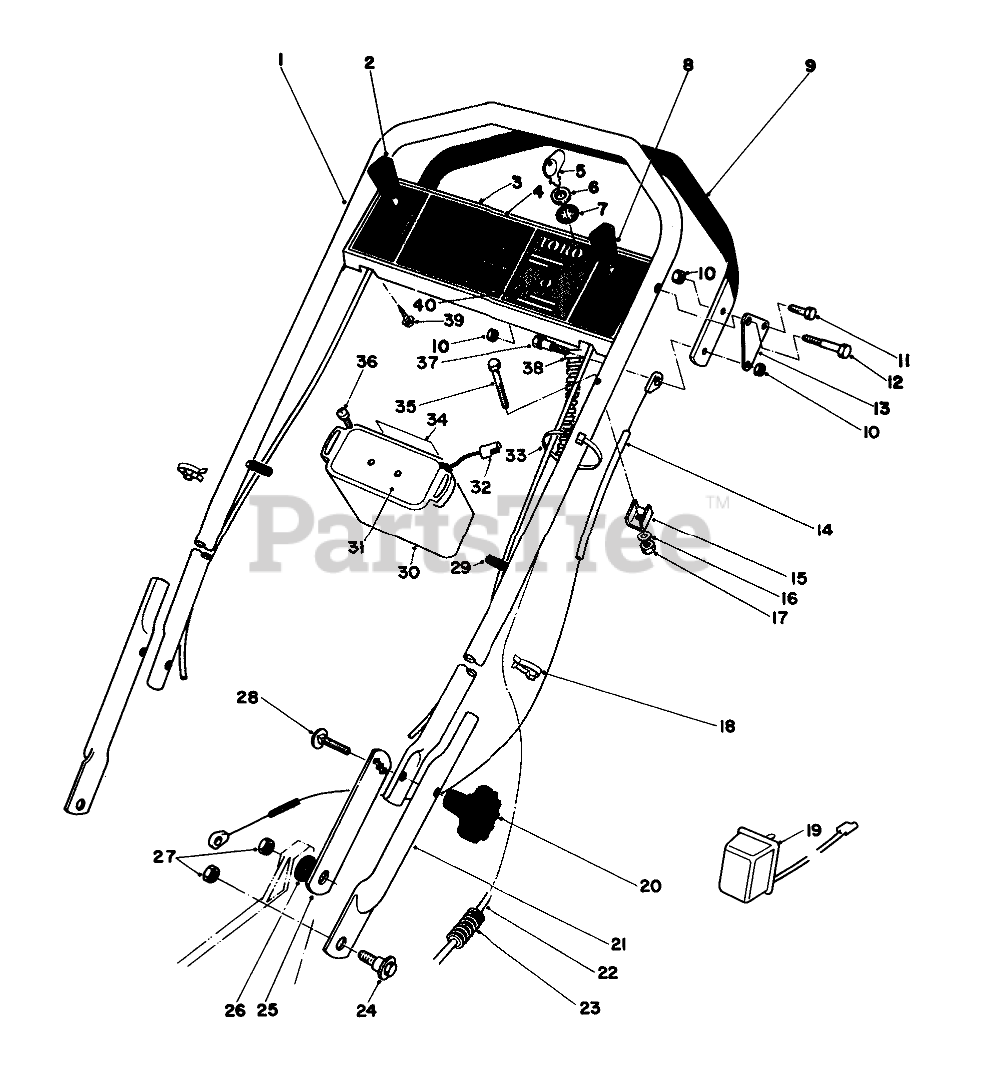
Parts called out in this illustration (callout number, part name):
1	Upper Handle
2	Ground Speed Control
3	Control Panel (Incl. Ref. #4)
4	Decal-Control Panel
5	Key
6	NUT-HH
7	WASHER-TOOTH, INTERNAL
8	Throttle Control
9	DEMAND HANDLE ASM
10	NUT-LOCK, CONE
11	SCREW-HH
12	BOLT-SHOULDER
13	Bracket Demand
14	DEMAND HAND CABLE
15	CLAMP-CABLE
16	WASHER-FLAT
17	NUT-LOCK, NI
18	BOWDEN CLIP
19	Charger
21	LOWER HANDLE
22	WIRE HARNESS
23	Decal-Caution
24	SCREW-SHOULDER
25	HANDLE LATCH
26	HANDLE LATCH SPACER
27	Nut
28	SCREW-CARR
29	CAP-VINYL
30	Battery Case
31	BATTERY COVER
32	Plug & Wire
33	TIE-CABLE
34	Decal
35	SCREW-HH
37	SHOULDER BOLT
38	RING FITTING
39	SCREW-HWHTF
40	Starter Switch (Incl. Ref. #5-7)
